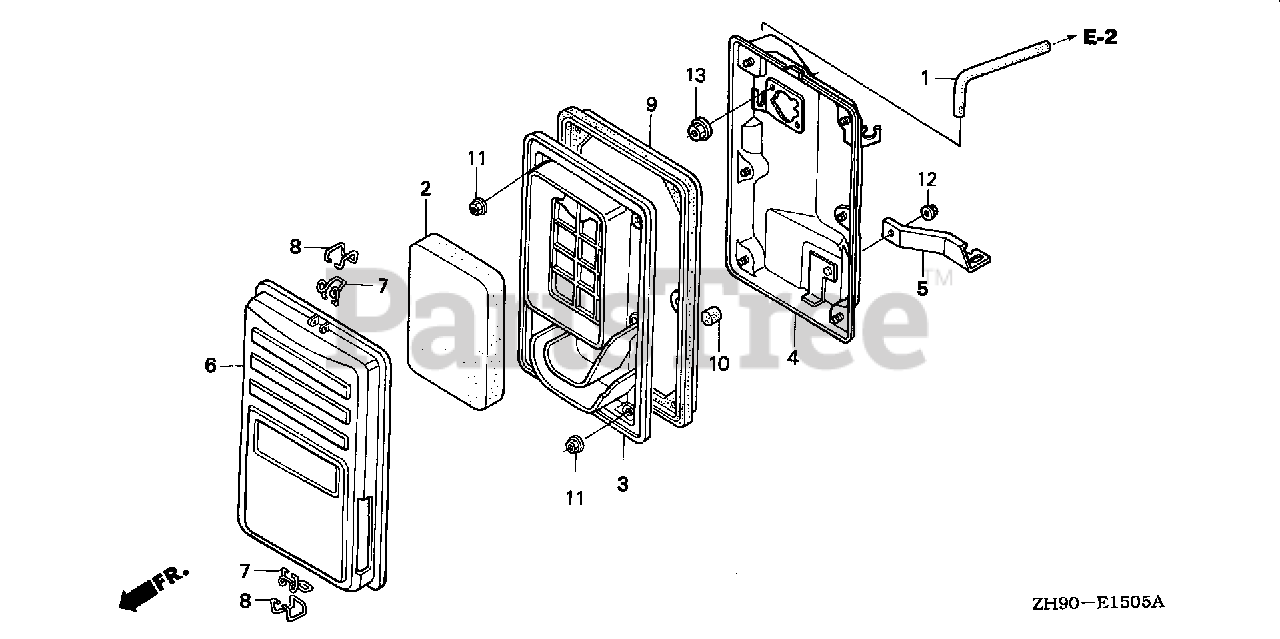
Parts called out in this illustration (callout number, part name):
1	TUBE, BREATHER
2	ELEMENT, AIR CLEANER
3	SEPARATOR, AIR CLEANER
4	HOUSING, AIR CLEANER
5	STAY, AIR CLEANER
6	COVER, AIR CLEANER
7	CLIP A, AIR CLEANER WIRE
8	CLIP B, AIR CLEANER WIRE
9	SEAL, AIR CLEANER
10	FILTER, DRAIN TUBE
11	NUT, FLANGE (5MM)
12	NUT, FLANGE (6MM)
13	NUT, FLANGE (6MM)
